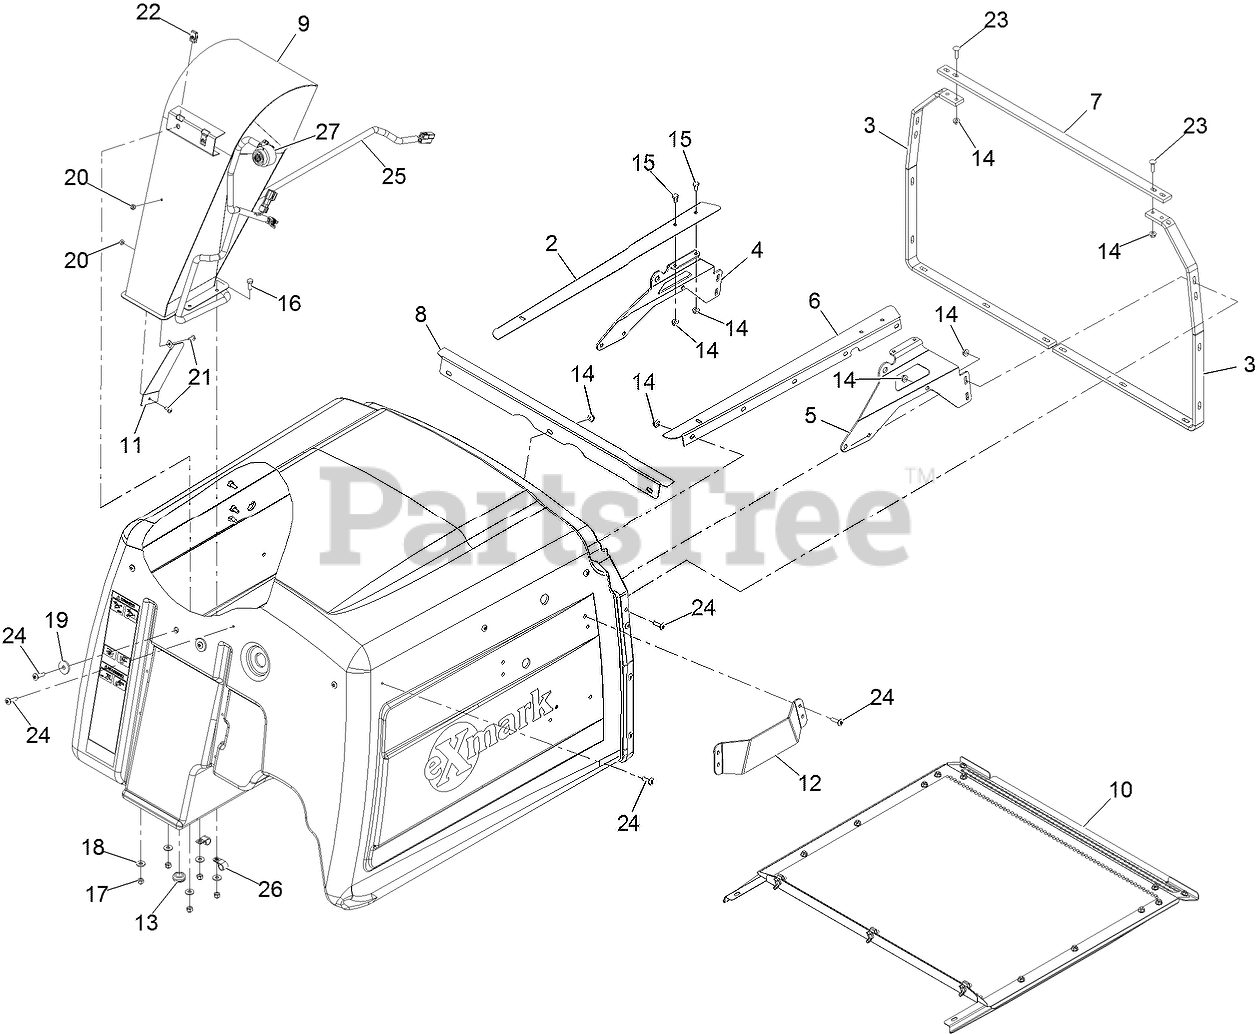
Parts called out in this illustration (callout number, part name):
2	ANGLE-SCREEN TRACK, RH
3	REINFORCEMENT-HOPPER
4	BRACE-DOOR PIVOT, RH
5	BRACE-DOOR PIVOT, LH
6	ANGLE-SCREEN TRACK, LH
7	BRACKET-FRAME CONNECT
8	CHANNEL-SCREEN, FRONT
10	HOPPER SCREEN ASM
11	DEFLECTOR-DISCHARGE CHUTE
12	PLATE-GUARD
13	GROMMET
15	SCREW-HH
16	SCREW-HH
17	NUT-LOCK, NI
18	WASHER-FLAT
20	NUT-LOCK, NI
21	SCREW-PTH
23	SCREW-CARR
24	SCREW-TTH
25	HARNESS-WIRE, HOPPER
26	CLIP-LOOM
27	ALARM-TONE, DUAL
